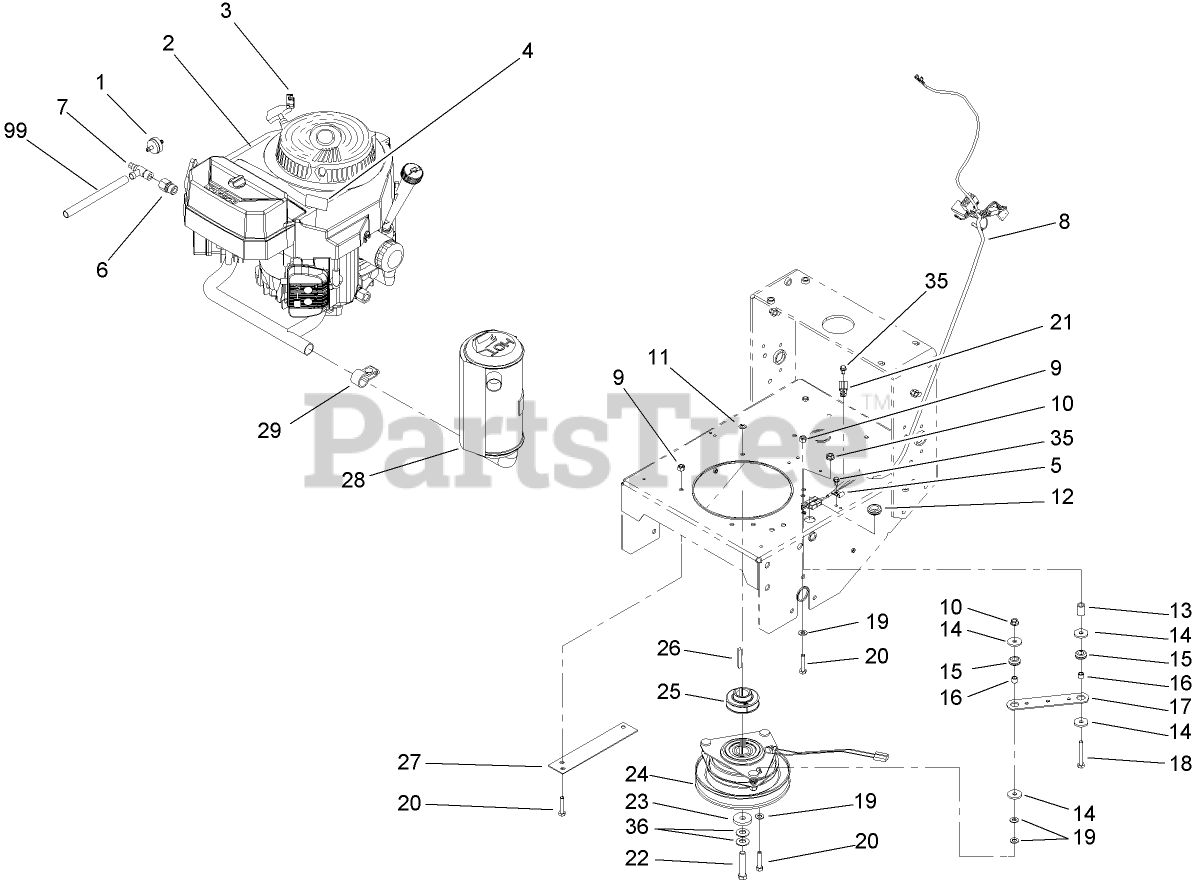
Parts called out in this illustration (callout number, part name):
1	FILTER-FUEL
3	CLAMP-CABLE
4	DECAL-WARNING
5	CLIP-CLOSED, INSULATED
6	Adapter
7	Valve-Drain, Oil
8	HARNESS-WIRE
9	NUT-LOCK, NI
10	NUT-HF
11	WASHER-LOCK
12	GROMMET
13	TUBE-RETAINER
14	WASHER
15	GROMMET
16	SPACER
17	STRAP-CLUTCH, BRAKE
18	SCREW-HH
19	WASHER-PLAIN
20	SCREW-HH
21	CLAMP-R
22	SCREW-HH
23	WASHER
24	CLUTCH / BRAKE ASM
25	PULLEY-DRIVE
26	KEY-SQUARE
27	COVER-PULLEY
28	MUFFLER
29	CLAMP-MUFFLER
35	SCREW
36	WASHER-SPRING
99	HOSE-DRAIN, OIL
